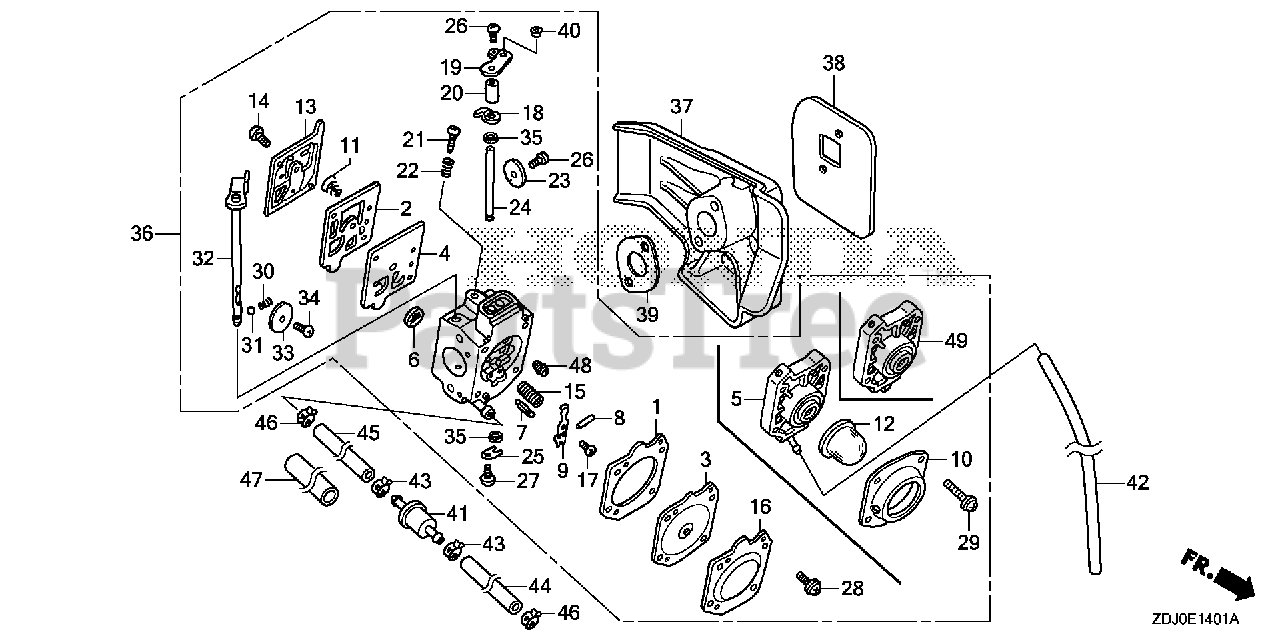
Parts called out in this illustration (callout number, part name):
1	GASKET, METERING DIAPHRAGM (CARBURETOR NO.)
2	GASKET, PUMP
3	DIAPHRAGM ASSY., METERING (CARBURETOR NO.)
4	DIAPHRAGM, PUMP
5	BODY ASSY., AIR PURGE (CARBURETOR NO.)
6	SCREEN, INLET (CARBURETOR NO.)
7	VALVE, INLET NEEDLE
8	PIN, METERING LEVER
9	LEVER, METERING
10	COVER, PRIMER PUMP (CARBURETOR NO.)
11	SPRING, PUMP
12	PUMP, PRIMER (CARBURETOR NO.)
13	COVER, PUMP (CARBURETOR NO.)
15	SPRING (CARBURETOR NO.)
17	SCREW (CARBURETOR NO.)
18	STOPPER, THROTTLE LEVER
19	LEVER, THROTTLE (CARBURETOR NO.)
20	SPACER, THROTTLE LEVER
21	SCREW, IDLE ADJUSTING (CARBURETOR NO.)
23	VALVE, THROTTLE (CARBURETOR NO.)
24	SHAFT, THROTTLE (CARBURETOR NO.)
25	CLIP, THROTTLE SHAFT
26	SCREW, VALVE
27	SCREW ASSY. (CARBURETOR NO.)
29	SCREW ASSY. (CARBURETOR NO.)
32	SHAFT ASSY., CHOKE (CARBURETOR NO.)
33	VALVE, CHOKE (CARBURETOR NO.)
36	CARBURETOR ASSY. (HDA-323)
37	INSULATOR, CARBURETOR
38	GASKET, INSULATOR
39	GASKET, CARBURETOR
40	COLLAR, LEVER
41	STRAINER, FUEL
42	TUBE, FUEL RETURN
43	CLAMP, TUBE (D9.4)
43	CLIP, TUBE (D8.5)
44	HOSE, FUEL (4.2X270) (FKM)
45	HOSE, FUEL (4.2X300) (FKM)
46	CLIP, TUBE (D8.5)
48	JET (#44)
48	JET (#46) (CARBURETOR NO.)
48	JET (#48) (CARBURETOR NO.)
48	JET (#50) (CARBURETOR NO.)
